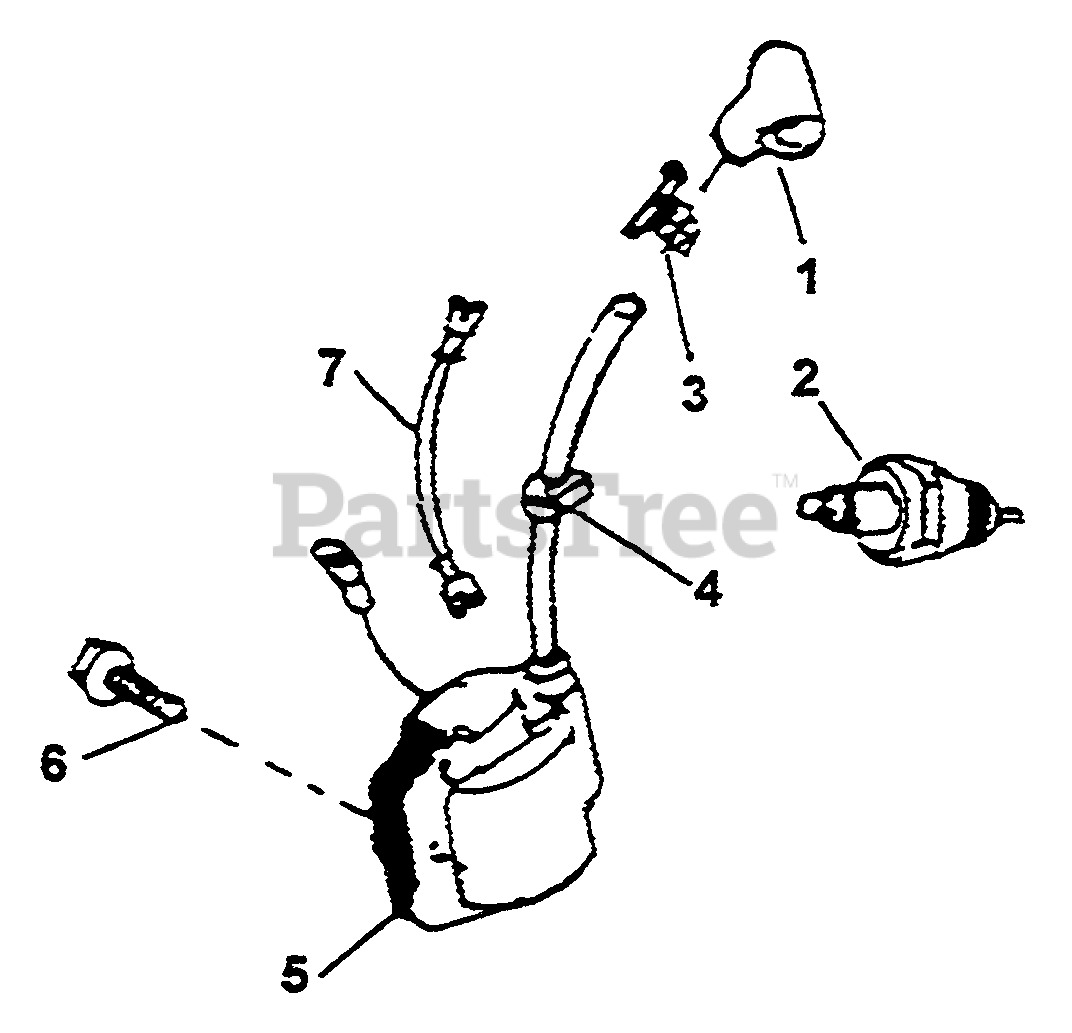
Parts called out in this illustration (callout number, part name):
2	SPARK PLUG
3	CONNECTOR
5	COIL, IGNITION
7	WIRE GROUND
